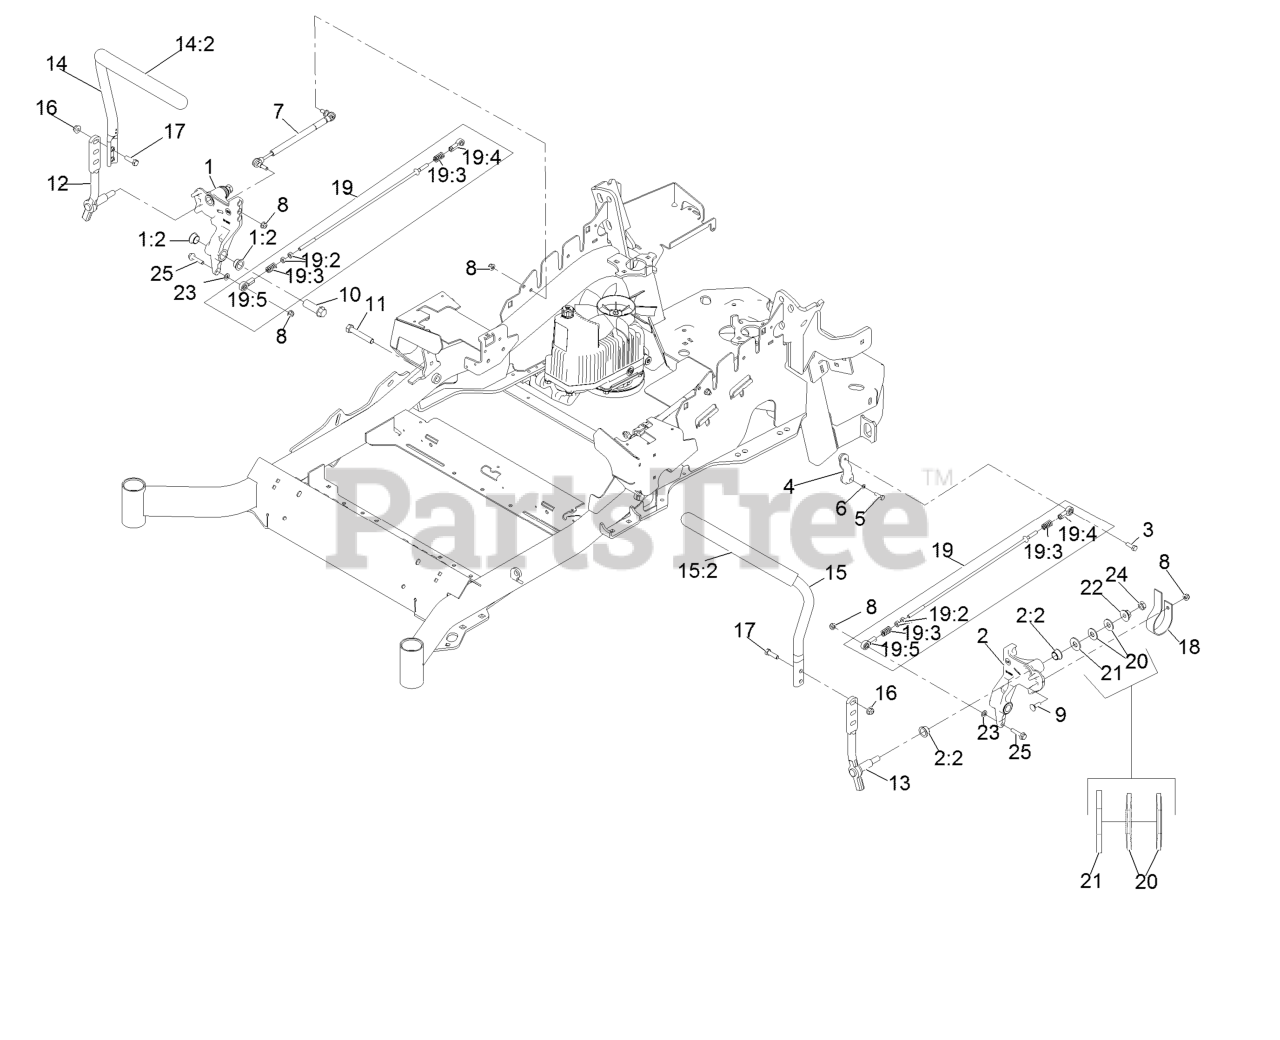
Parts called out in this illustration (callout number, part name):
1	RH Motion Control And Bushing ASM
1:2	Bushing-Flanged
2	LH Motion Control And Bushing ASM
2:2	Bushing-Flanged
3	Screw-HH 5/16-18 X 1 W/Patch
4	Arm-Control, Pump
5	Screw-HH 1/4-20 X 7/8
6	Washer-Spring Disc 1/4
7	Damper-Control, Motion
8	Nut-Nyloc 5/16-18 Flg
9	Bolt-Carriage 5/16-18 X 1
10	Hub-Threaded
11	Screw-HH 1/2-13 X 3
12	Lever-Control Motion, RH
13	Lever-Control Motion, LH
14	RH Steering Handle ASM
14:2	Grip-Control, Lever
15	LH Steering Handle ASM
15:2	Grip-Control, Lever
16	Nut-Nyloc 3/8-16 Flg
17	Screw-HH 3/8-16 X 1 1/4
18	Spring-Leaf
19	Pump Linkage Rear ASM
19:2	Nut-Hex 5/16-24
19:3	Spring-Compression
19:4	Balljoint
19:5	Balljoint
20	Washer, Spring Disc 1/2
21	Washer
22	Nut-Hex 1/2-13 Flange
23	Washer-5/16 SAE
24	Nut-Jam 1/2-13
25	Screw-Hex Flange 5/16-18 X 1 1/2
